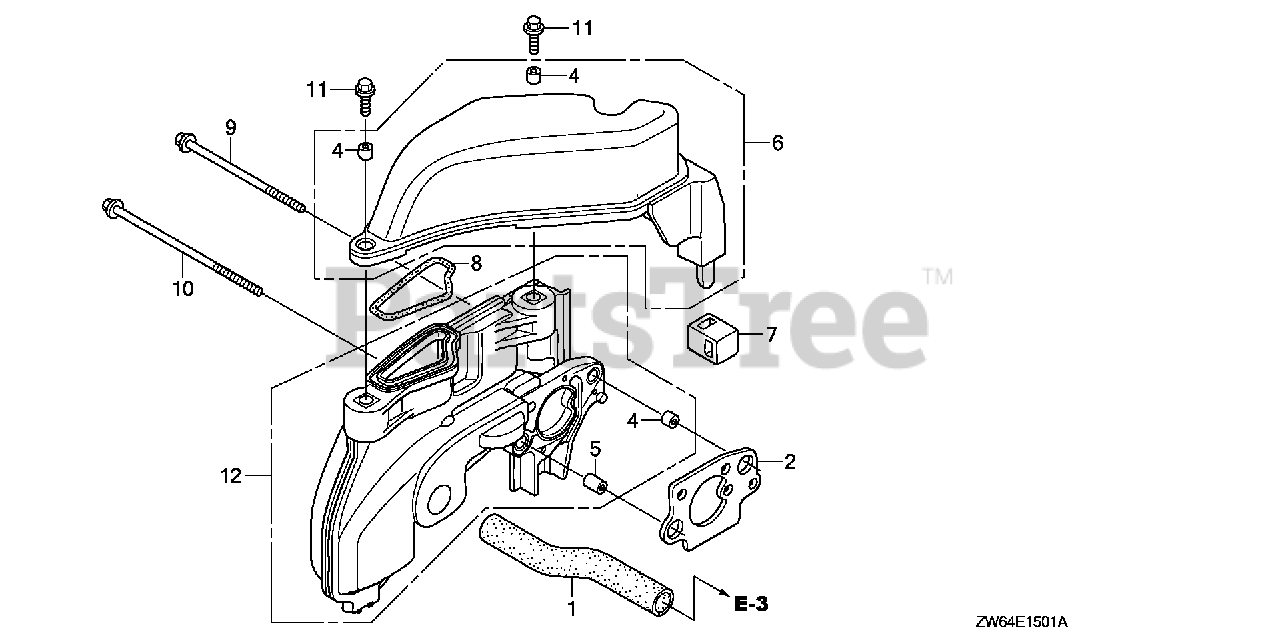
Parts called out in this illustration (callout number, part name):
1	TUBE, BREATHER
2	GASKET, AIR GUIDE
3	GUIDE ASSY., AIR
4	COLLAR, DISTANCE
5	COLLAR, DISTANCE (14MM)
6	CASE, MUFFLER
7	GROMMET, MUFFLER
8	SEAL, MUFFLER
9	BOLT, FLANGE (5X62)
10	BOLT, FLANGE (5X70)
11	BOLT, FLANGE (5X12)
12	GUIDE, AIR INLET
